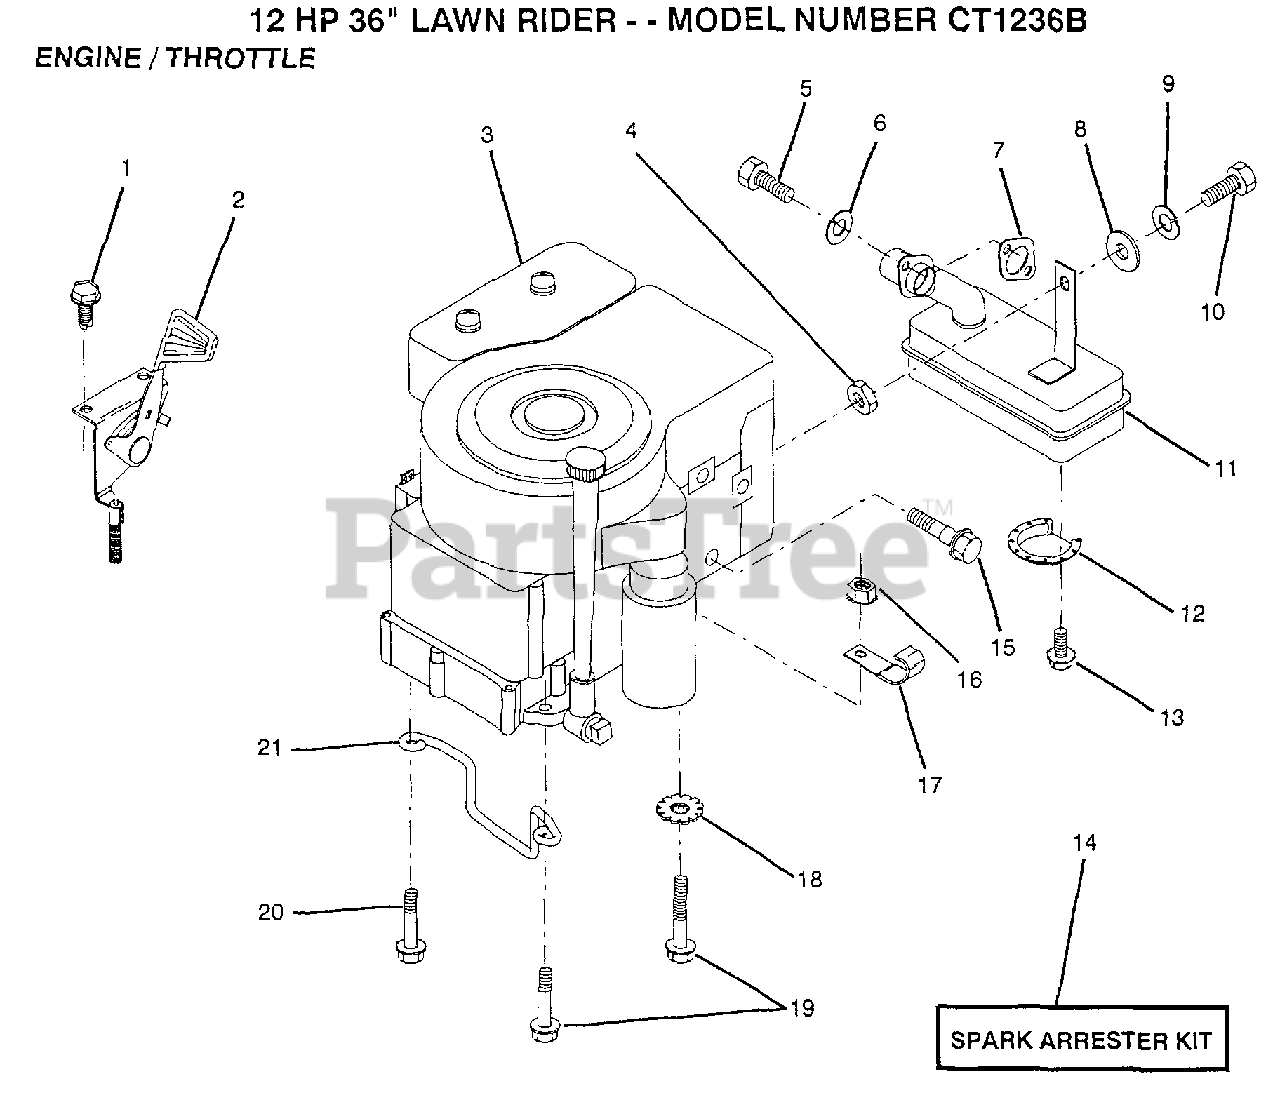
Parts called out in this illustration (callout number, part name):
1	SCREW
3	ENGINE BRIGGS AND STRATTON
4	NUT.HEX.5/16-18
5	SCREW
6	LOCKWASHER
9	LOCKWASHER
10	BOLT
11	MUFFLER
12	DEFLECTOR.222573
15	BOLT T
16	NUT
17	CLIP T
18	LOCKWASHER
19	SCREW LT
20	SCREW LT
21	"KEEPER,DR BELT GR"
